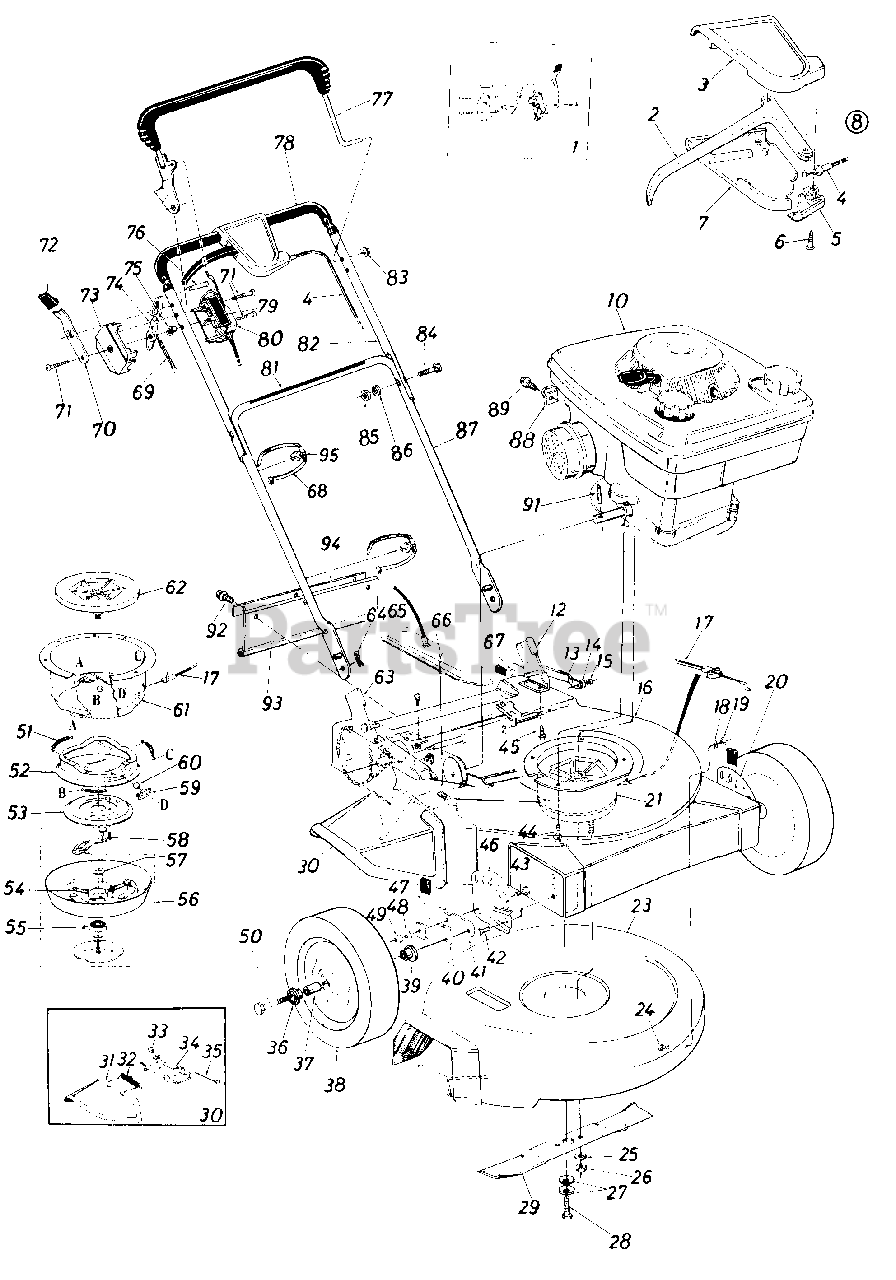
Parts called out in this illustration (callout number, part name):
1	Control Housing Comp.
2	Control Lever
3	Control Cover Half-Upper
4	Drive Clutch Cable-59"
5	Cable Mounting Cap
6	Flat "C" Sunk Hd. Tap Scr. #10 x .75" Lg.
7	Control Cover Half-Lower
8	Clutch Control Housing Comp.
10	Engine
12	Handle Mount Brkt. Ass'y.-L H
13	Pivot Brkt. Ass'y.-L.H.
14	Belleville Wash. .400" I.D. x .88"
15	Hex Nut 5/16-18 Thd.*
18	L-Wash. 5/16" I.D.*
19	Hex Nut 5/16-18 Thd.*
20	Height Adj. Ass'y. Comp.-L.H.
21	Blade Brake/Clutch Ass'y.-Comp.
23	Lower Deck Ass'y.
24	Carriage Bolt 5/16-18 x .62" Lg.*
25	L-Wash. 3/8" I.D.*
26	Hex Nut 3/8-24 Thd. (Grade 8)
27	Belleville Wash.
28	Hex Bolt 3/8-24 x 2.00" Lg. (Grade 8)
29	21" Blade
30	Chute Deflector Ass'y.-Comp.
31	Chute Deflector
32	Torsion Spring
33	Push Nut 1/4" Rod
34	Adapter Plate
35	Pivot Pin
36	Ball Bearing 3/8" I.D.
37	Spacer
38	Wheel Ass'y. Comp. 8 x 1.75
39	Ball Bearing 1/2" I.D.
40	Bell-Wash. .400" I.D. x .88"
41	Pivot Bar
42	Hex Sems Bolt 3/8-16 x .62" Lg.
43	Shoulder Bolt
44	Hex Wash. Hd. TT-Tap Scr. 3/8-16 x 1" Lg.
45	Hex Wash. Hd. "B'-Tap Scr. 5/16 x 1/2" Lg.
46	Height Adjuster Ass'y. Comp.-R.H.
47	Spring Lever Ass'y. w/Knob
48	Bell-Wash. .400" I.D. x 1.13"
49	Hex Ins. L-Nut 3/8-24 Thd.
50	Axle Bolt
51	Extension Spring
52	Brake Cup Cone
53	Clutching Cone
54	Compression Spring
55	Ball Bearing
56	Clutch Blade Housing Ass'y.
57	Fl-Wash. .69" I.D. x 1.06" O.D.
58	Hex TT-Tap L-Scr. 1/4-20 x .75" Lg.
59	Ball Block
60	Steel Ball 1/2" Dia.
61	Clutch Housing
62	Fan Adapter
63	Handle Mount Brkt. Ass'y.-R.H .
64	Internal Cotter Pin 5/16" Dia.
65	Belt Cover
66	Hex Wash. Hd. "AB" Tap Scr. #10 x .50" Lg.
67	Index Plate Ass'y.-L.H.
68	Cable Tie
69	Throttle Wire-43"
70	Lockout Spring
71	Truss Mach. Tap Scr. #12 x 1.5" Lg.
72	Spring Lever Knob
73	Control Panel Half
74	Throttle Control Lever
75	Control Disc Pin
76	Lock Pin
77	Control Handle-R.H.
79	Control Label-Throttle
80	Clutch Panel Half
81	Instruction Label-Handle
82	Upper Handle (Chrome)
83	Cap Speed Nut 5/16" Rod
84	Curved Carriage Bolt 5/16-18 x 1.38" Lg.
85	Hex Nut 5/16-18 Thd.*
86	L-Wash. 5/16" I.D.*
87	Lower Handle (Chrome)
88	Casing Clamp
89	Hex Sems Scr. #10-32 x .62" Lg.
91	Spring Pin 3/16" Dia. x 1.5" Lg.
92	Hex Wash. Hd. AB-Tap Scr. 1/4 x.62" Lg.
93	Rear Flap
94	Retaining Strip
95	Cable Anchor
